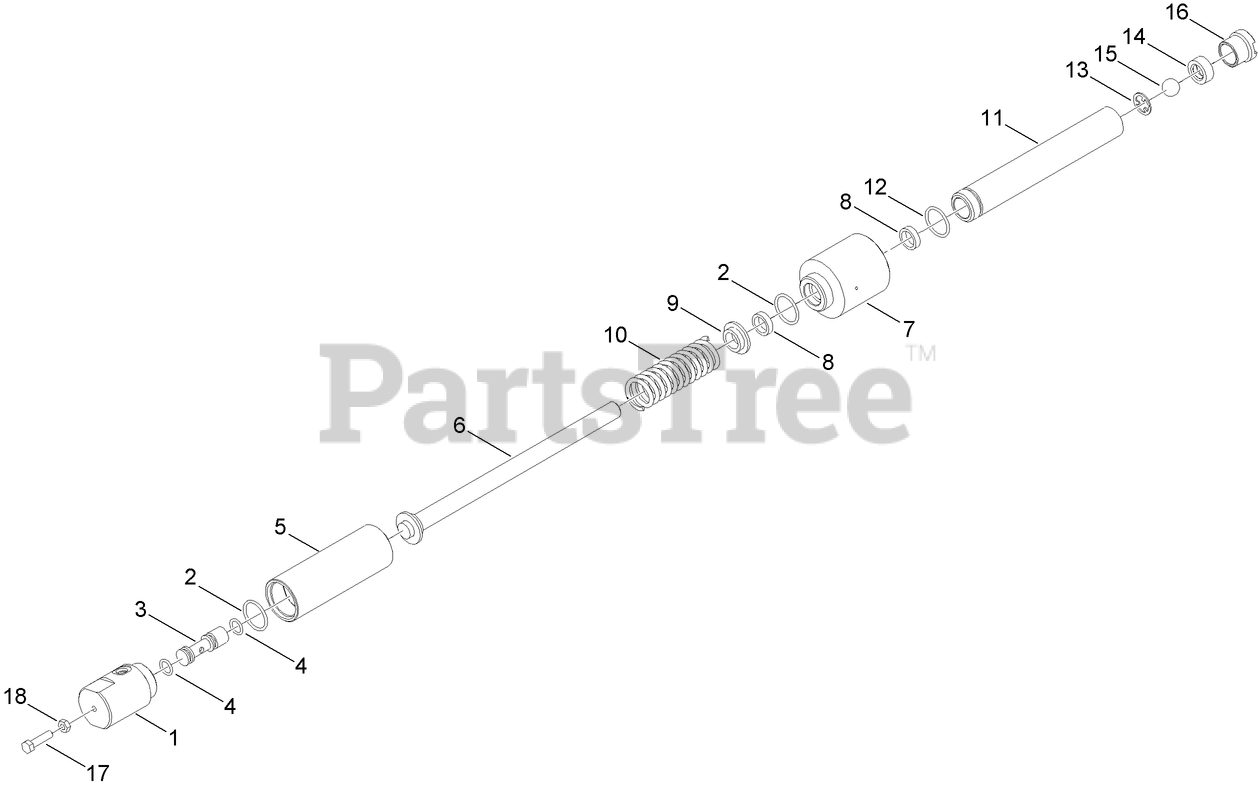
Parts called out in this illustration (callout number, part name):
1	CAP-CYLINDER
2	SEAL-O RING
3	SPOOL-ADJUSTING
5	BARREL-CYLINDER
6	PLUNGER
7	BODY-PUMP
8	SEAL-DEEP
9	GUIDE-ROD
10	SPRING
11	BARREL-PUMP
12	SEAL-O RING
13	CLIP-RETAINER
14	VALVE-SEAT
15	BALL-STEEL, STAINLESS
16	TUBE-INLET
17	SCREW-HH
18	NUT-JAM
